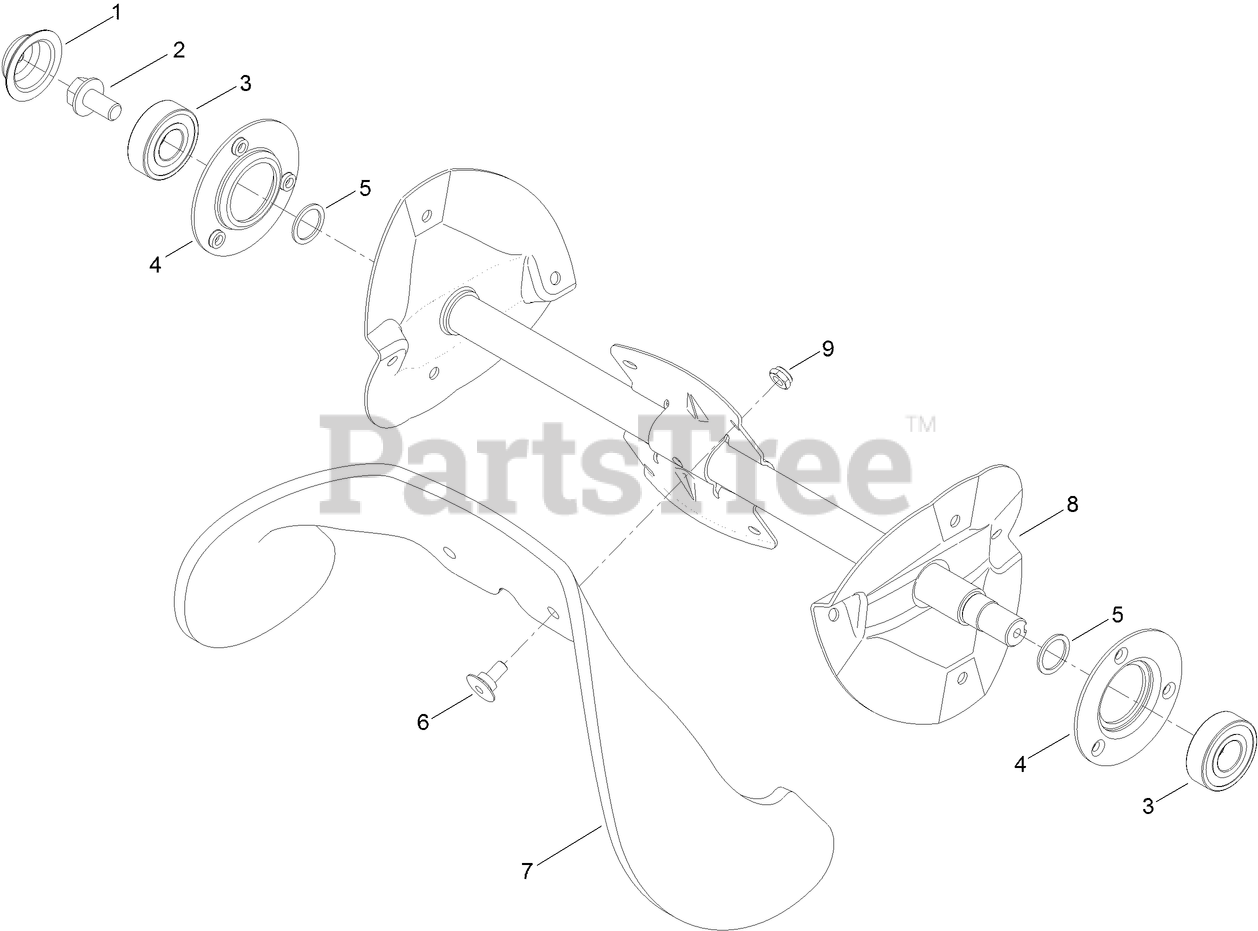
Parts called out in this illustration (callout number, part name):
1	CAP-SIDEPLATE, RH
2	SCREW-HWH
4	FLANGE-BEARING
5	WASHER-THRUST
6	SCREW
7	BLADE-ROTOR
8	ROTOR ASM
9	NUT-LOCK, NI
